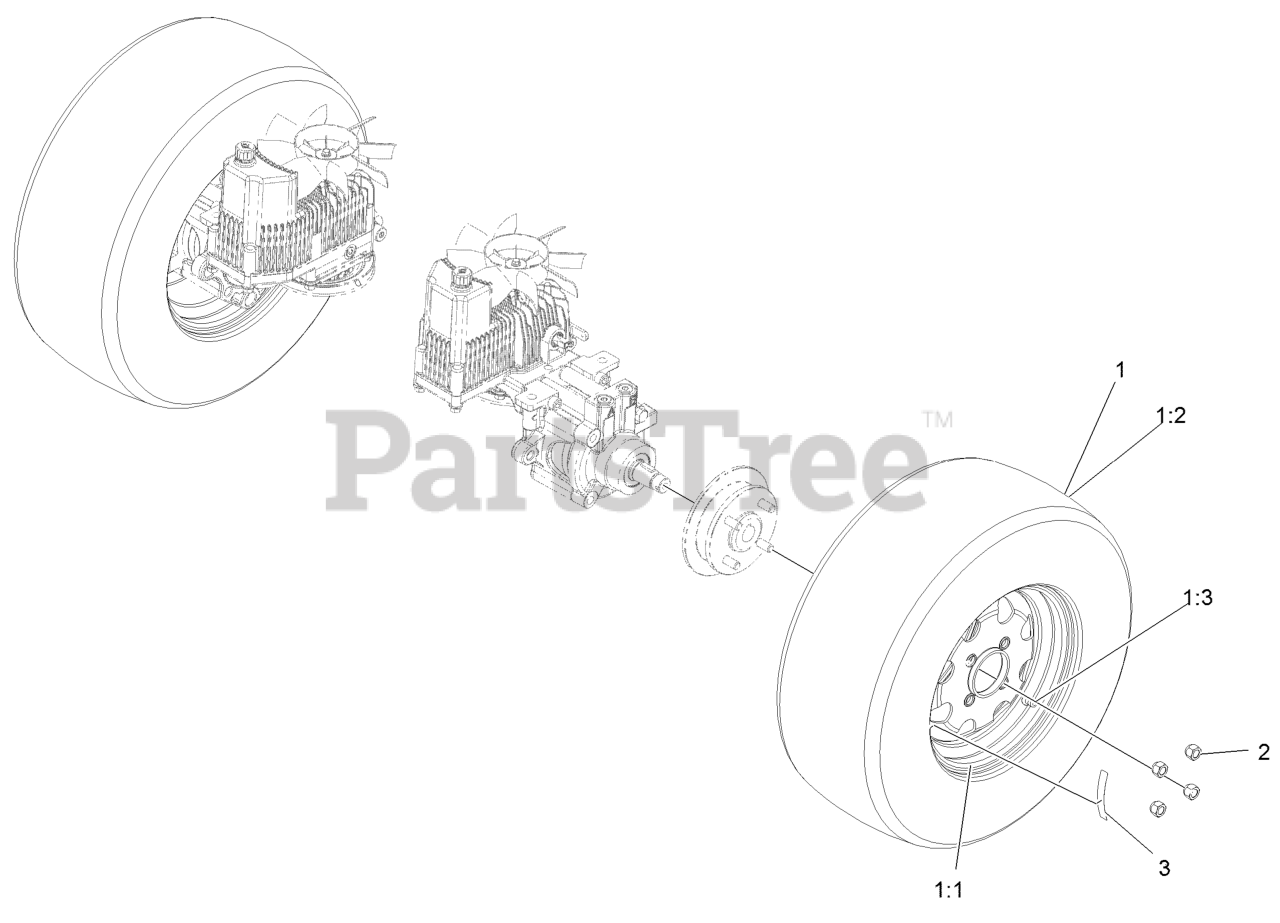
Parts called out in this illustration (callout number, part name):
1	KIT-SUSPENSION SEAT
2	ISOLATOR-SEAT
3	NUT-HF, NI
4	PLATE-TILT, SEAT SUPPORT
5	SCREW-CARR
6	NUT-HF, NI
7	PLATE-FRAME, SEAT
9	MOUNT-SEAT
9:2	DECAL-CONSOLE
9:3	DECAL-SERVICE AID
10	PLATE-LATCH, SEAT
11	BOLT-CARR
12	SPRING-COMPRESSION
15	SCREW-SHOULDER
16	ROD-PROP
17	WASHER-PLAIN
